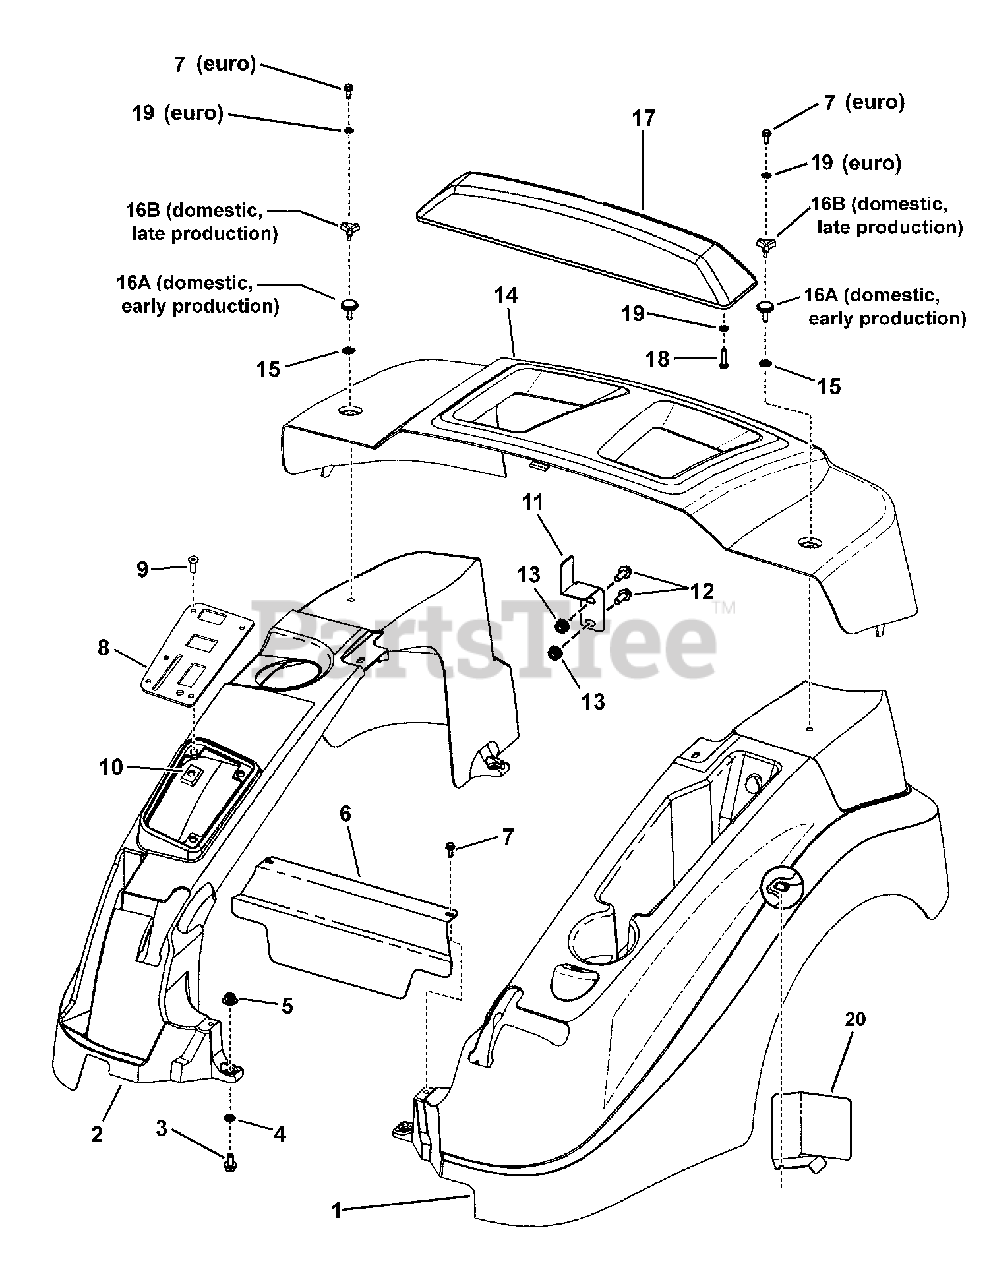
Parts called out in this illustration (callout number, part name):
1	FENDER, LH RZT
2	FENDER, RH RZT
3	BOLT, 5/16-18 x 5/8" Hex Flange Lock, GR 5
4	BOLT RETAINER, 5/16" Black
5	NUT, 5/16-18 Hex Large Flange Center Lock
6	COVER, Front, Snapper
7	SCREW, 1/4-20 x 5/8" Hex Washer Self-Tap, YZ
8	PANEL, Control
9	SCREW, 1/4-20 x 5/8" Pan Head Self-Tap (Torx)
10	U-NUT 1/4-20
11	BRACKET, RH Fender Support
12	BOLT, 5/16-18 x 7/8" Hex Flange Lock, YZ
13	NUT, 5/16-18 Hex Flange Lock, GR 5
14	COVER, Engine, Double Vent
15	WASHER, 1/4" Internal/External Tooth Lock
16A	KNOB (1/4-20 thread)
16B	3-PRONG KNOB, 1/4-20 x 1/2"
17	GUARD, Rear Seat
18	SCREW, 1/4-15 x 1-1/4" Hex Washer Self-Tap
19	WASHER, .28 x .63 x .06 Flat, GR 5
20	HEAT SHIELD, Fender, ERZT/EJAV
